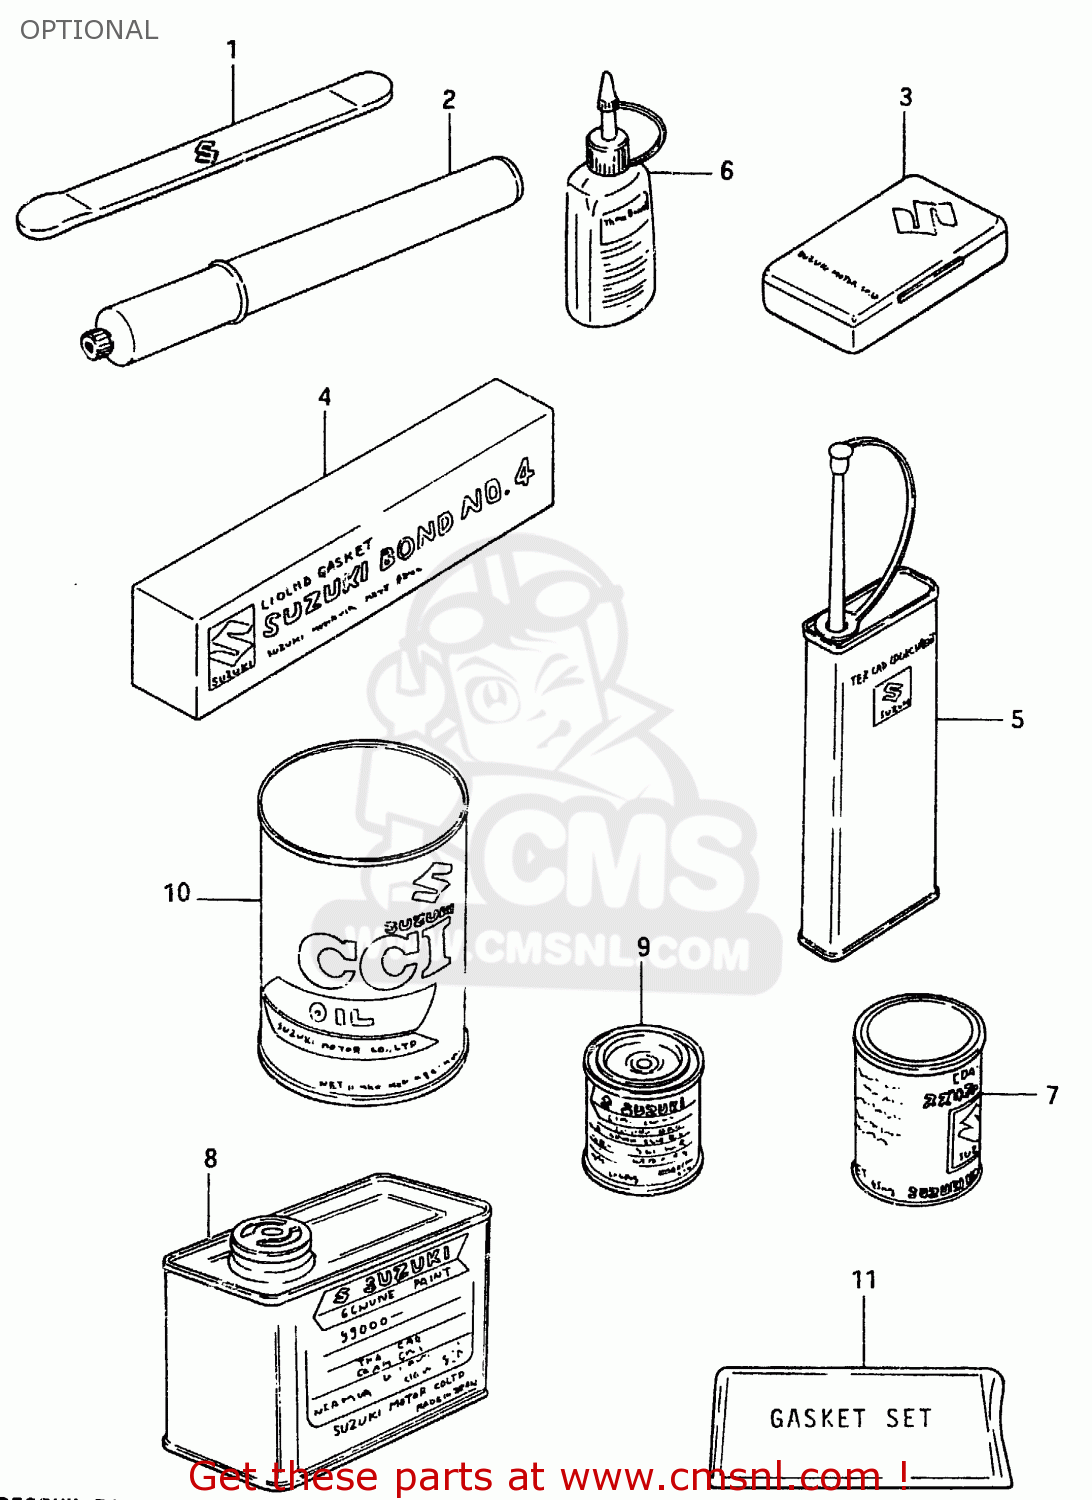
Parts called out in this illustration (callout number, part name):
1	LEVER,TIRE
2	INFLATOR, AIR
3	TUBE REPARING TOOL
4	BOND 1104
5	THREAD LOCK NO.1401 CLEAR 200G
6	THREAD LOCK NO.1303B PURPL 50G
7	GREASE(C)EP2 LITHIUM 150G
8	PAINT (BLACK)
9	PAINT,BLACK
10	CCI OIL
11	GASKET SET
